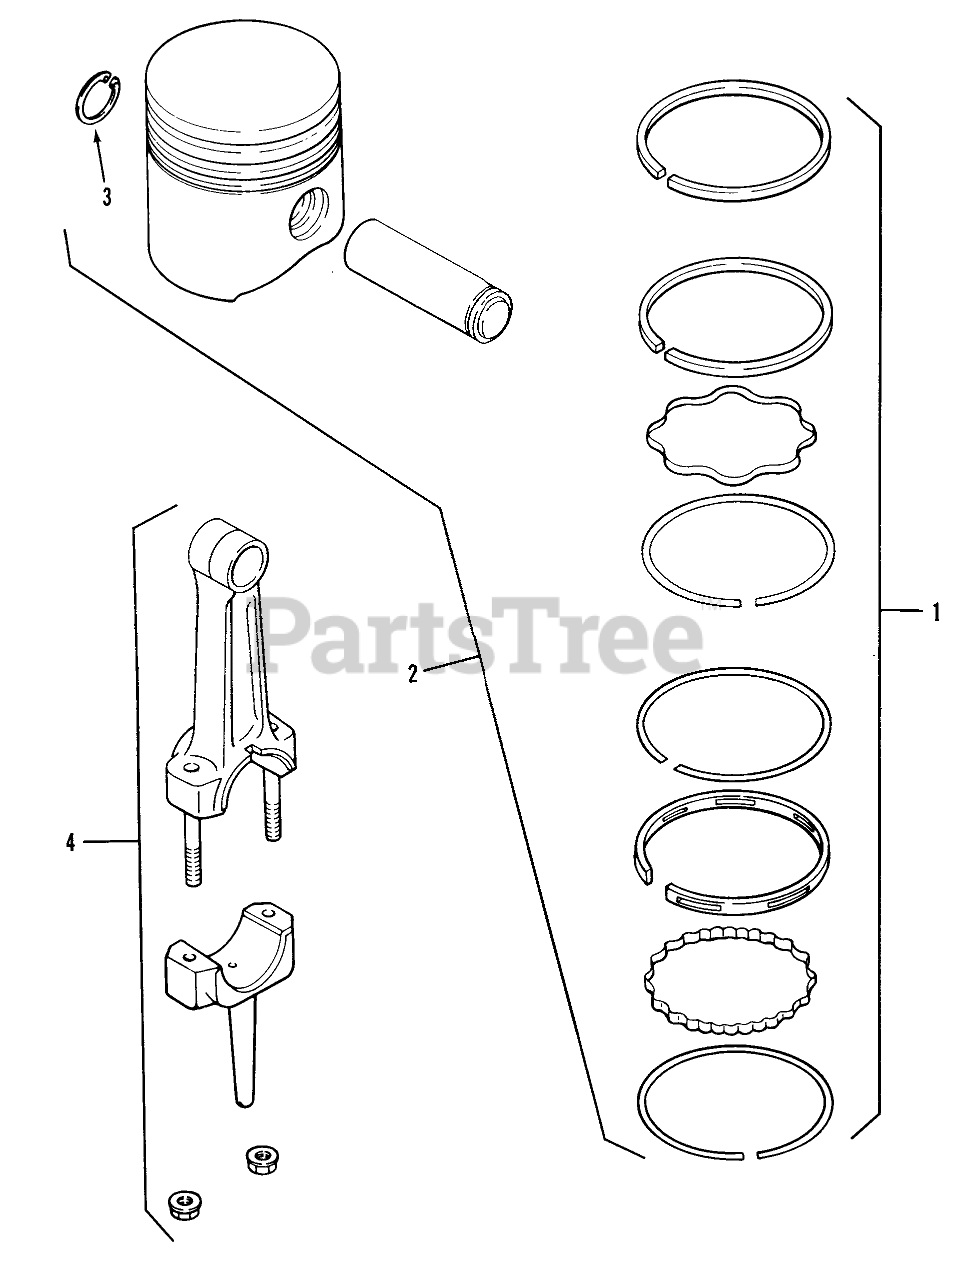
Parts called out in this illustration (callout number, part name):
1	Ring set-Std. & 003 (Svc.)
2	Piston w/Ring Set Std. 310
3	Retainer-Piston Pin
4	Connecting Rod Std. 310
